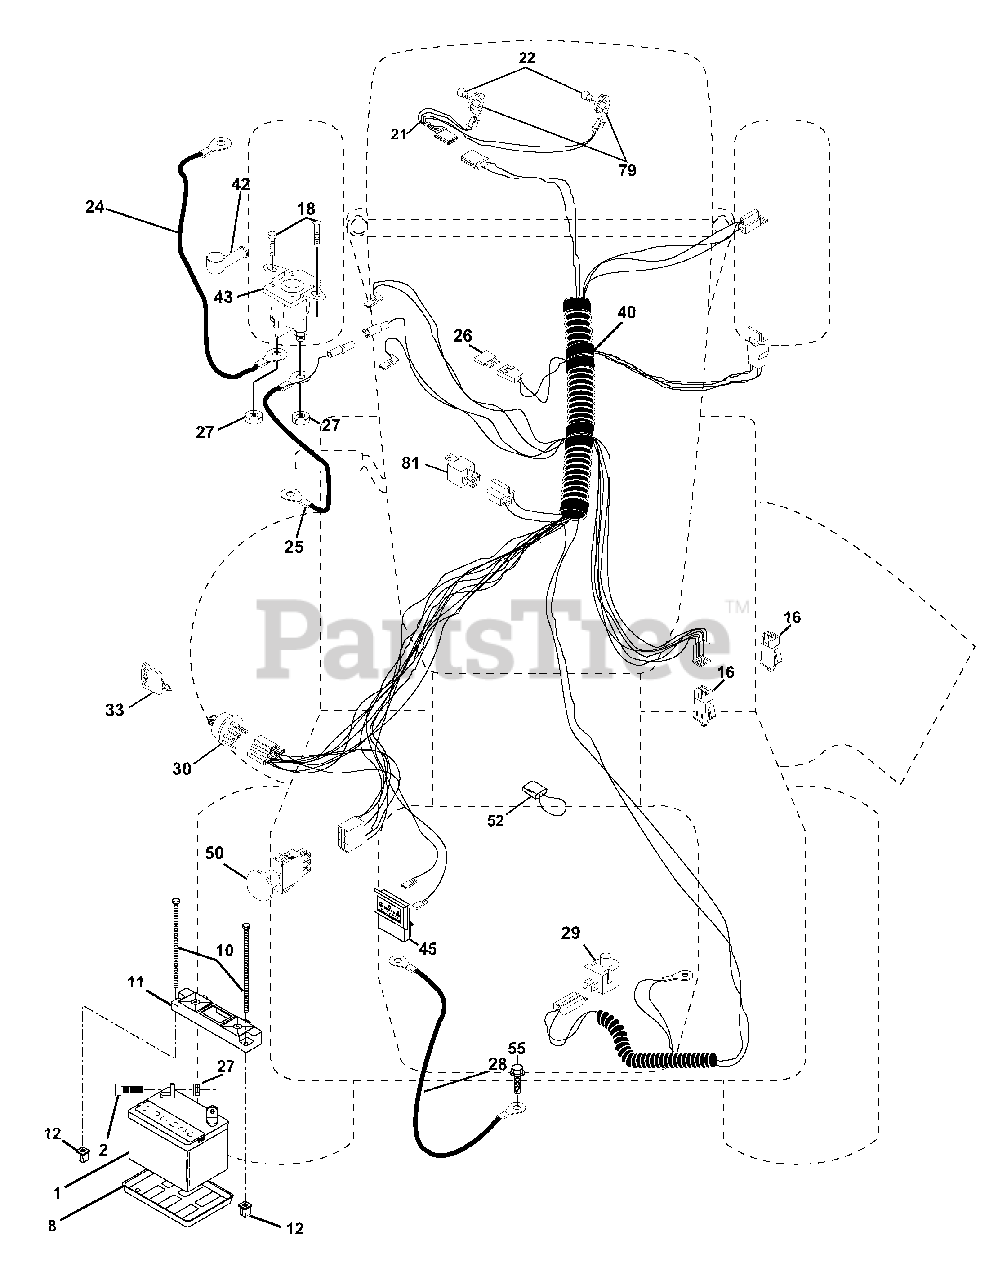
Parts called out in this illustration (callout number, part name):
1	Battery
2	Bolt Hex Hd 1/4-20 UNC X 3/4
8	Tray, Battery
10	Bolt, BTR FRT 1/4-20 x 7.5
11	Hold Down Battery, Front
12	Nut, Push, Nylon
16	Switch Interlock Push-In
18	Screw Thd 1/4-20 x 1/2
21	Harness Asm Light W/4152j
22	Bulb Light #1156
24	Cable Battery
25	Cable Batterywire
26	Fuse
27	Nut Keps Hex 1/4-20 Unc
28	Cable Ground
29	Switch Plunger Normal OP Olive
30	Switch Ign 4 pos w/lights
33	Key Ign
40	Harness Ign.
42	Cover Terminal Red
43	Solenoid
45	Ammeter Rectangular
50	Switch, PTO
52	Protection Wire Loop
55	Screw Thdrol 5/16-18 x 1/2
79	Bulbholder
81	Relay Asm
